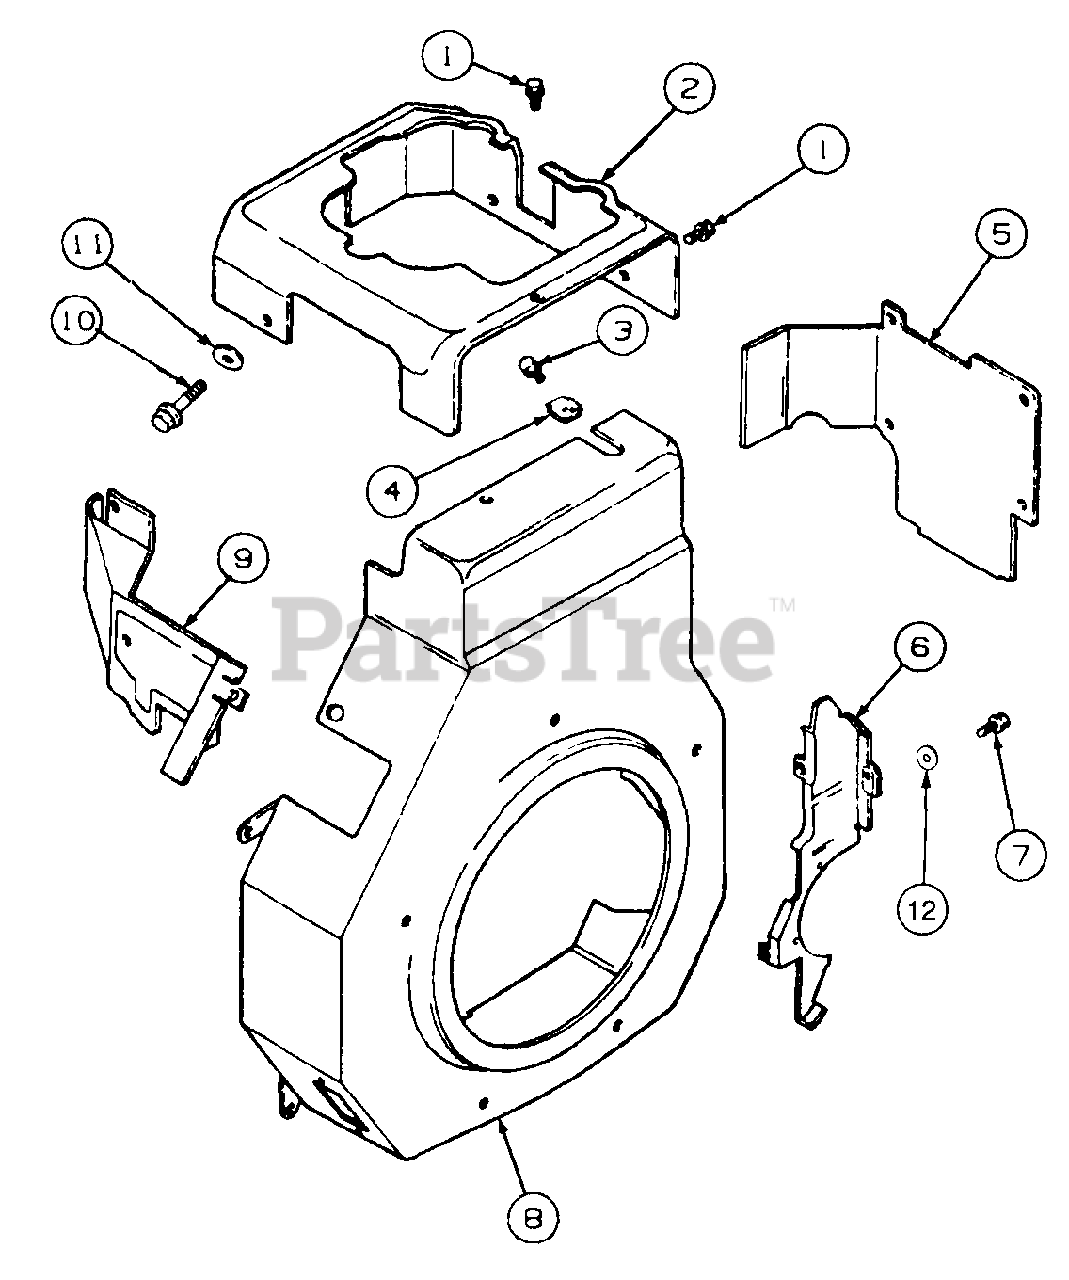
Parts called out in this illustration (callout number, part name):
1	Screw, Hex Flange, M5 x .8 x 10
2	Baffle, Cylinder Head
3	Screw, Hex Flange, M5 x .8 x 16
4	Clip, Mounting
5	Baffle, Cylinder
6	Plate, Blower Housing
7	Screw, Hex Flange, M5 x .8 x 20
8	Housing, Blower
9	Baffle, Intake Side
10	Screw, Hex Head
11	Washer, Plain
12	Washer, Plain 1/4"
